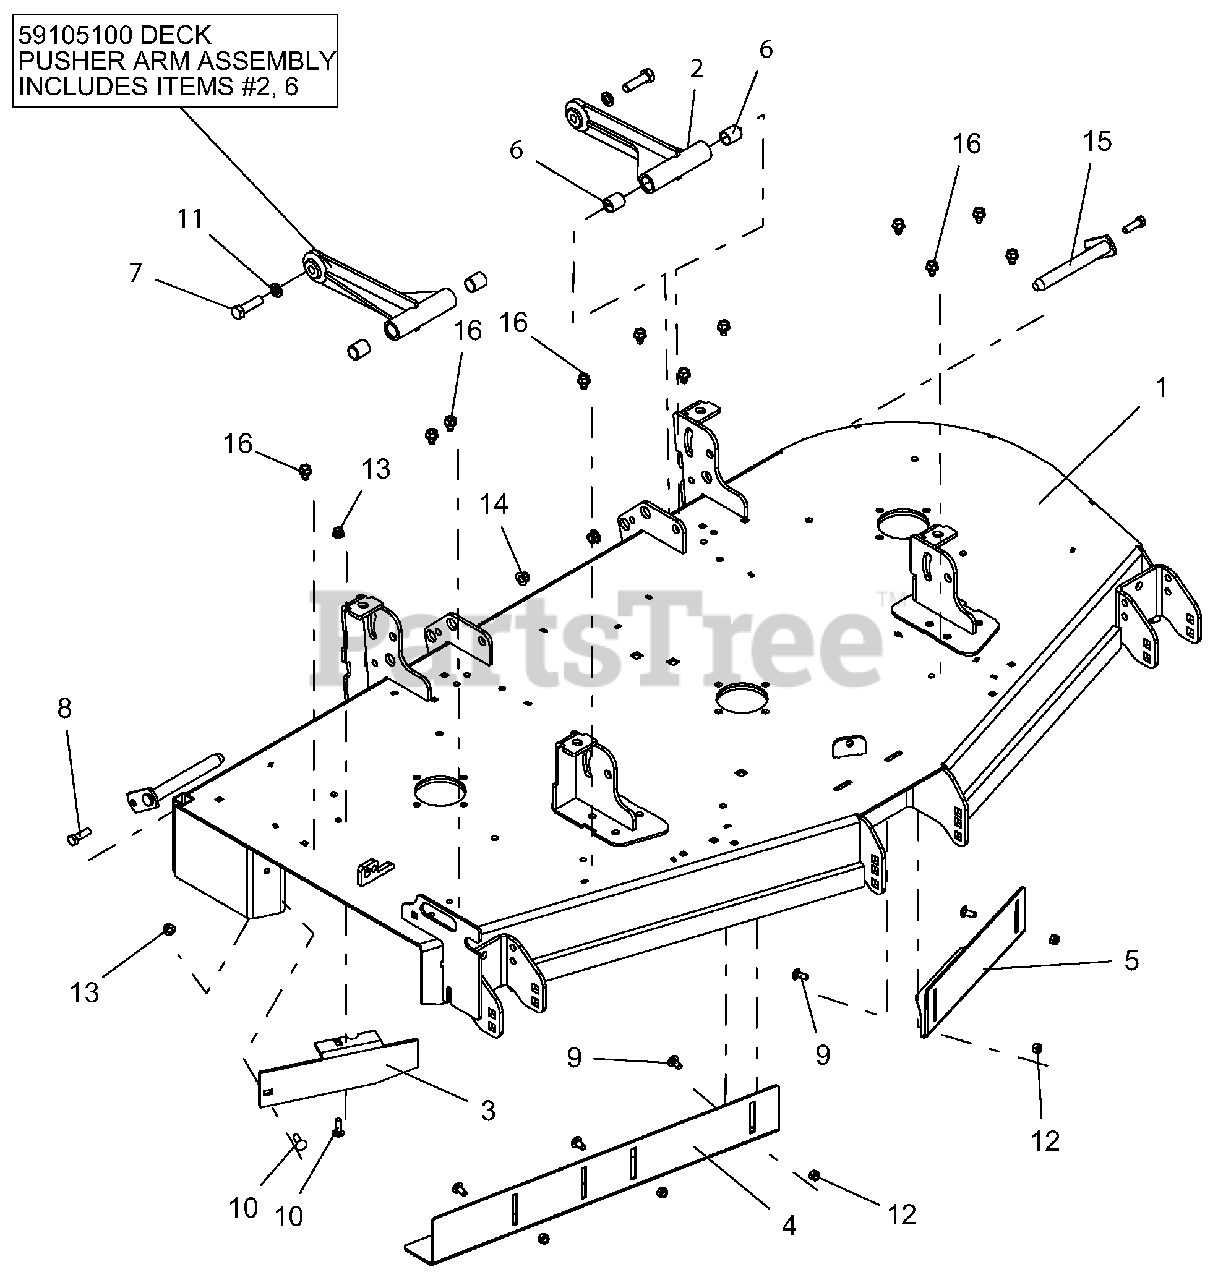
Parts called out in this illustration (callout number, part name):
1	KIT, PT160 MOWER DECK W/SAFETY DECALS-RED
2	WLDMT, DECK PUSHER ARM
3	BAFFLE, 60" DISCHARGE
4	BAFFLE, 60" RH VACUUM
5	BAFFLE, 60" LH VACUUM
6	BRG, .75 X .875 X 1.00
7	BLT-HEX .50-13X1.75 GR5 YWZC EP80
8	BLT-HEX .38-16X1.25 GR5 YWZC
9	BLT-RDHDSQNK .31-18X.75 G5 YWZC
10	BLT-RDHDSQSHNK .31-18X1.00 G5 Y
11	WSHR-LK .50X.125 REG YWZC
12	NUT-LK-NYL .312-18 YWZC
13	NUT-LK-NYL-FLG .31-18 YWZC
14	NUT-LK-NYL-FLG .38-16 YWZC
15	WLDMT, MOWER MTG. PIN
16	SCR-TAP .38-16X.50 HWH TR YWZ
